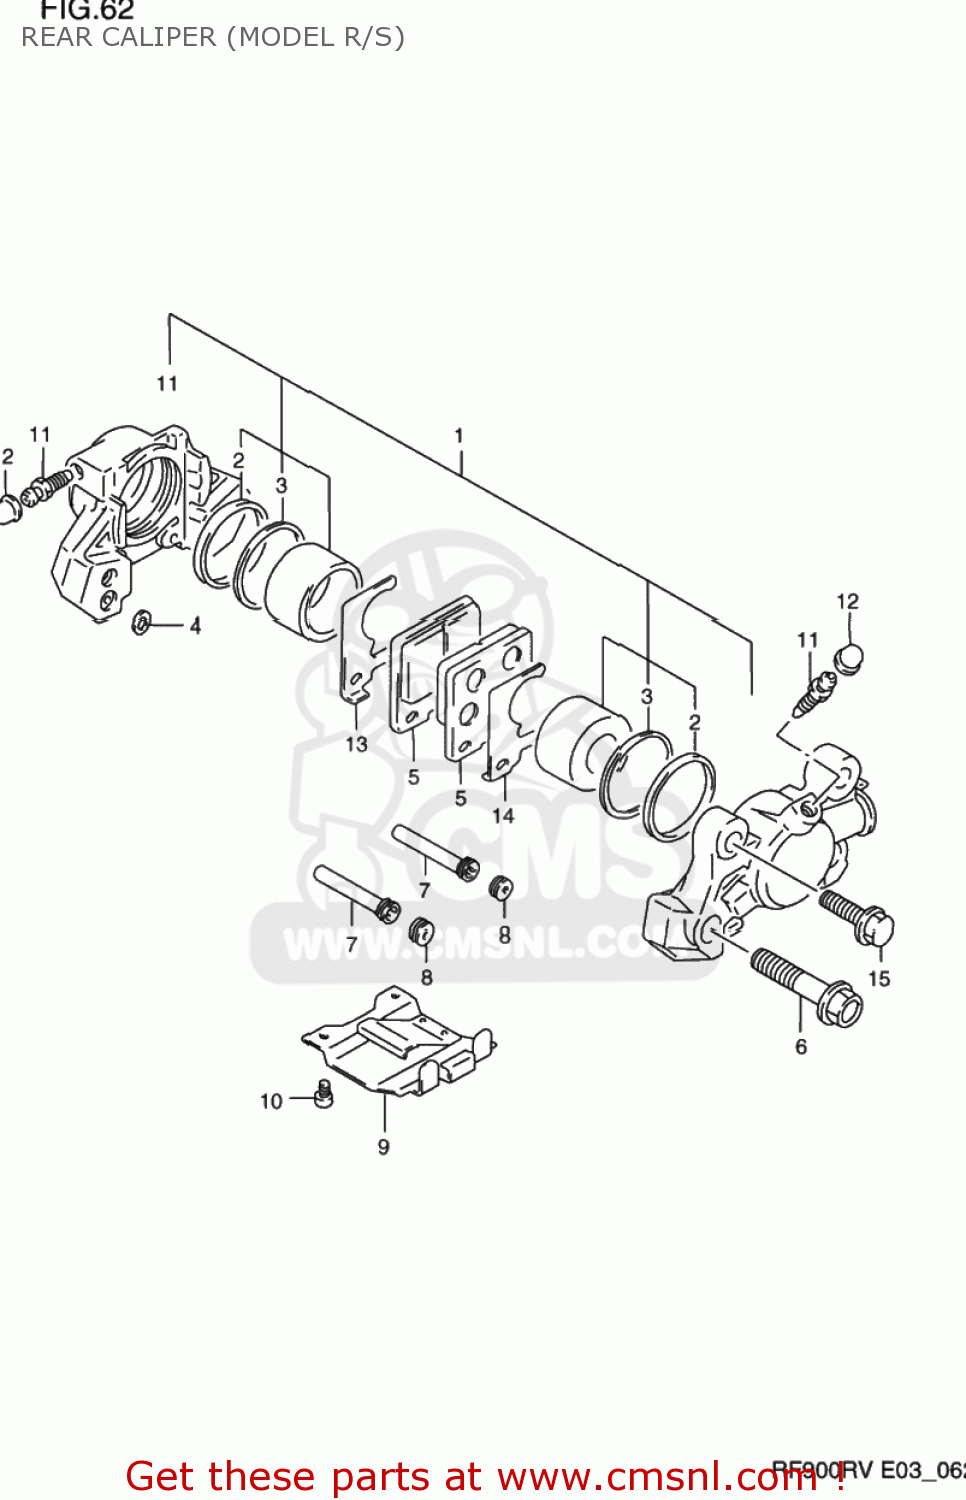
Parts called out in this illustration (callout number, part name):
1	PISTON SET
2	SEAL,PISTON
3	SEAL,WIPER
4	SEAL,JOINT
5	PAD,BRAKE
6	BOLT
7	PIN,PAD
8	PLUG,PAD PIN
9	COVER
10	SCREW
11	BLEEDER
12	CAP,BREATHER
13	SHIM,PAD,INNER
14	SHIM,PAD,OUTER
15	BOLT
